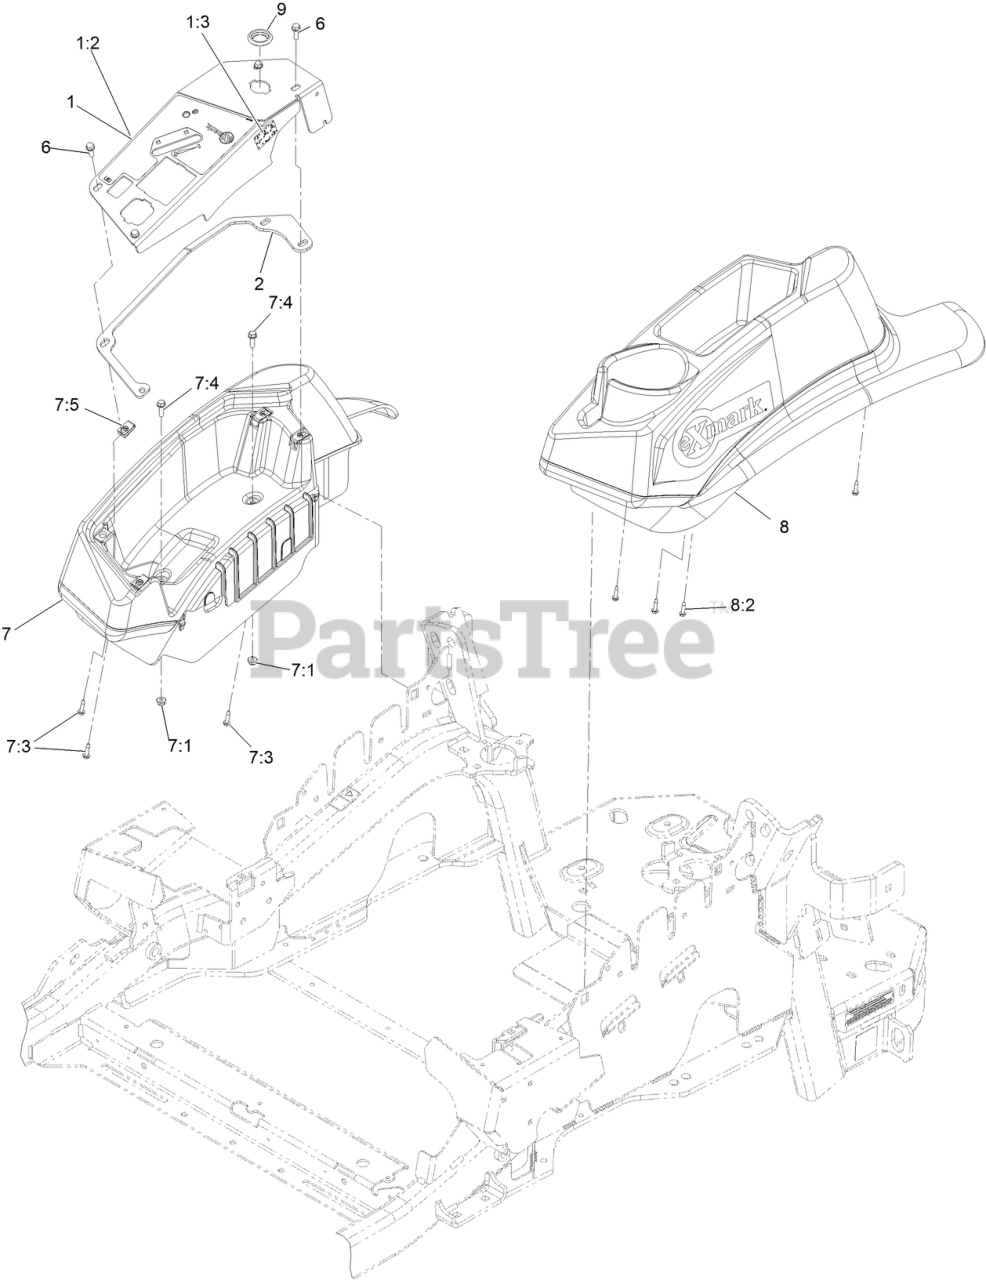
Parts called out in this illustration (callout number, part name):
1	ASM-CONTROL PANEL W/DECAL
1:2	DECAL-CONTROL PANEL
1:3	DECAL-FUSE
2	SPACER-CONTROL PANEL, KAW 820
6	SCREW-HWHTF
7	CONSOLE,RH NARROW ASM
7:3	SCREW,THD FORM,HWH
7:4	SCREW-HWH
8	CONSOLE.LH NARROW ASM
8:2	SCREW,THD FORM,HWH
9	PLUG-PLASTIC
